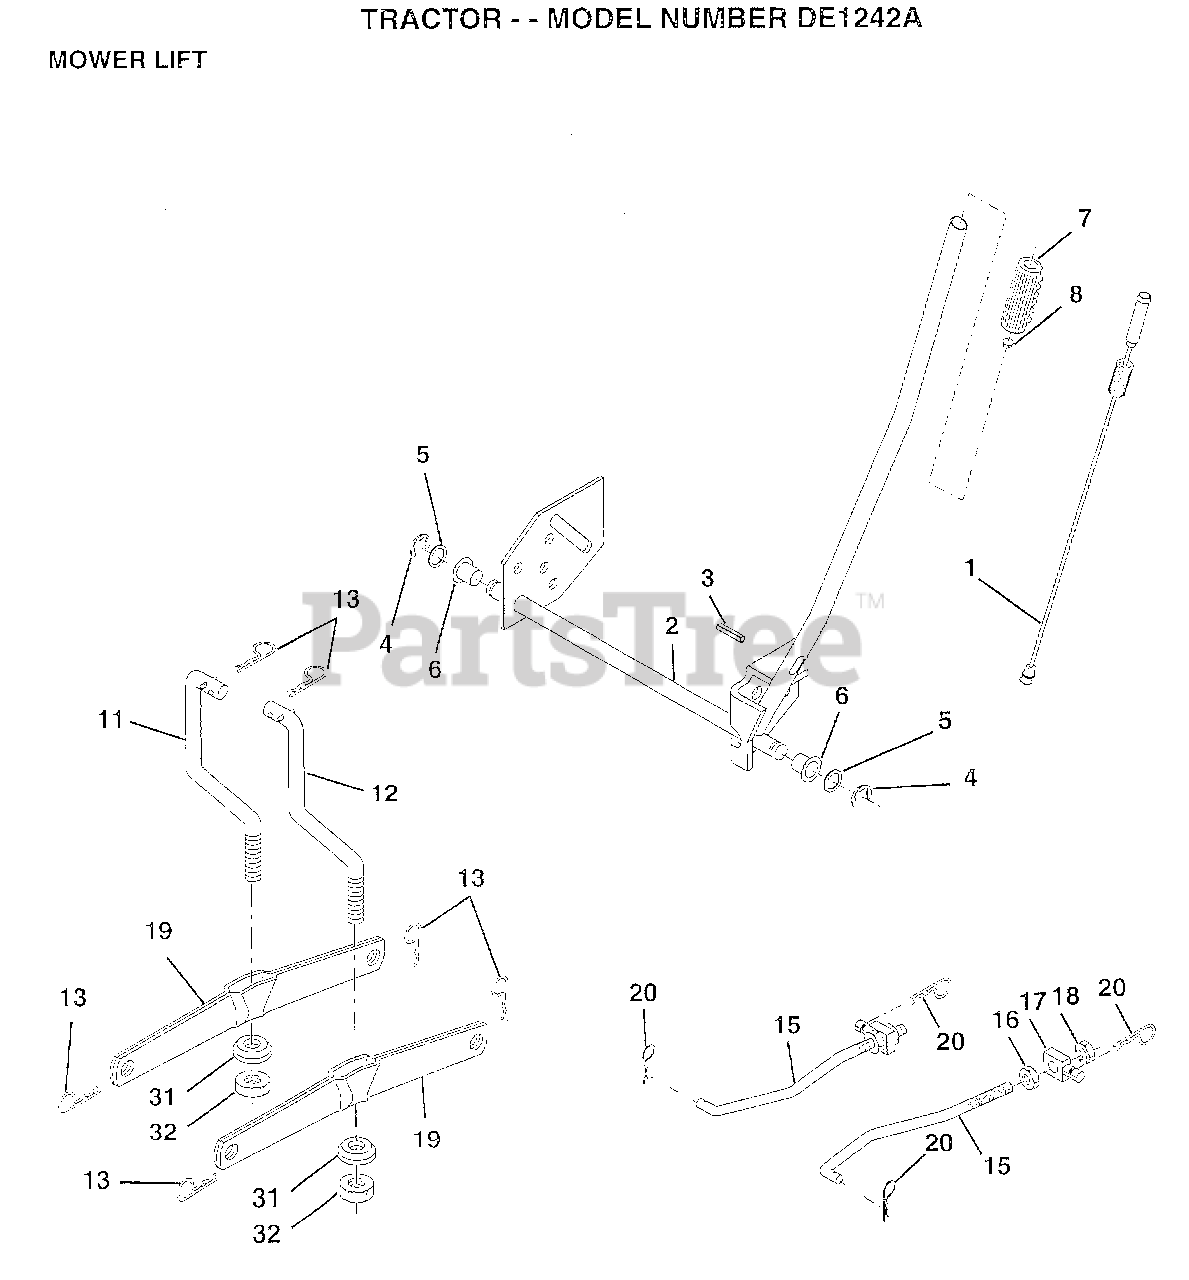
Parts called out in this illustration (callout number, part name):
1	WIRE ASM W.SPRING
2	"SHAFT ASM LIFT,RH"
3	PIN-GROOVE LT
5	WASHER
6	NYLON BEARING
7	GRIP
15	LINK.FRONT
16	NUT
17	TRUNION
18	NUT LTV
19	ARM SUSP REAR
20	RETAINER SPRING
31	BEARING PVT LH
32	NUT.CROWNLOCK.3/8
